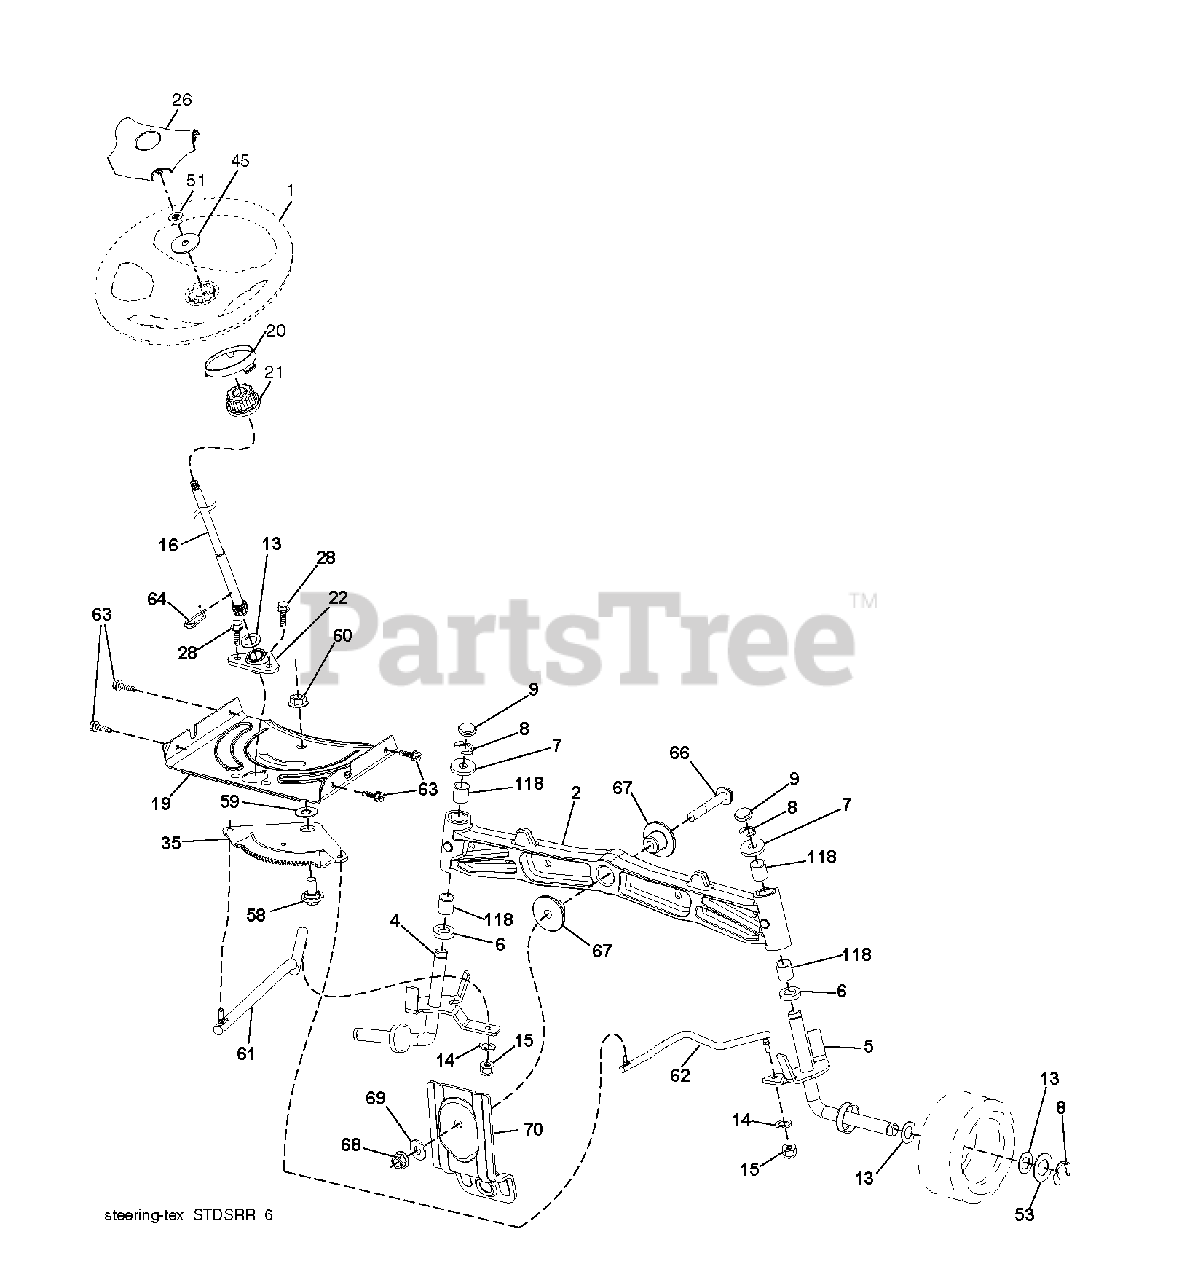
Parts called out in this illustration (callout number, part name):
1	WHEEL.STEERING.STDSRR.BLK/OV
2	AXLE.SVC.ASM CAST IRON.TEX
8	RING CLIP
9	CAP.SPINDLE
14	WASHER, LOCK 3/8
15	NUT CROWNLOCK 3/8-24
16	SHAFT.STEER.STEALTH.DD
19	PLATE.STEER.DDL.NLT/NG
21	ADAPTER, WHEEL STNG..
22	STEERING.SUPT.LOWER.
26	CAP.WHL.STRNG.STDSRRD.SRS.BLK
28	SCREW, 3/8-16X3/4
35	GEAR.SECTOR.PLATE.DDL.
45	WASHER 9/16"ID, 2 3/8"OD
51	NUT.HEX.1/2-20
53	WASHER.HARDENED
58	BOLT.SHOULDER.SECTOR.P
59	WASHER.THURST.SECTOR.S
60	NUT FLANGE LOCK 5/8-11
61	DRAGLINK.LH.BALLSTUD.D
62	DRAGLINK.RH.BALLSTUD.D
63	SCREW
64	RETAINER.CLIP.SPRING.S
66	BOLT HEX FGHD 7/16-14 X 3 SERR
67	BUSHING.PM.FRONT AXLE
68	NUT.LOCK.FLANGE.7/16
69	WASHER.1.5X.505X.118
70	BRKT.DECK.SUSPENSION.F
118	BUSHING, AXLE CAST
